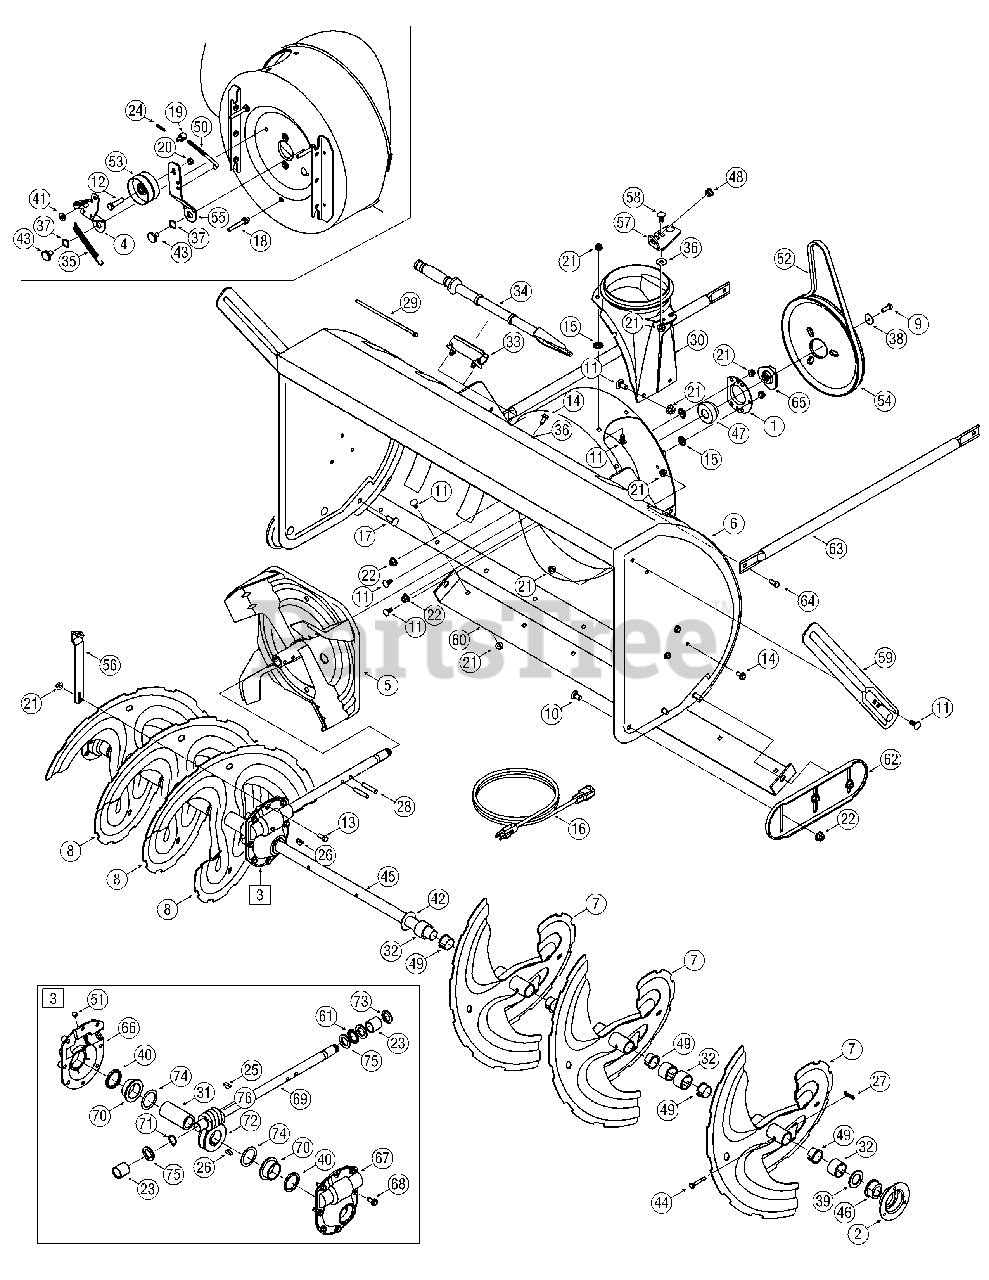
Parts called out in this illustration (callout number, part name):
1	Housing, Bearing
3	Gear Box Assembly, Auger
4	Bracket Assy, Auger Brake
9	Screw, 5/16-24 x .875
10	Bolt, Carriage, 3/8-16 x .750
11	Screw, Carriage, 5/16-18 x .75
12	Scr, Hex Cap, 3/8-24 x 1.5
13	Scr,Hex Cap, 5/16-18 x 1.00
14	Screw, 5/16-18 x .750
15	Nut, Push
16	Extension Cord, 110V
17	Bolt, Carriage, 3/8-16 x 1.0
18	Screw, 5/16-18 x .4300
19	Ferrule
20	Nut, Hex Lock, 3/8-24
21	Nut, Flnge Lk, 5/16-18
22	Nut, Flg Lk, 3/8-16
23	Sleeve
24	Pin, Internal Cotter
25	Key, Hi Pro, 3/16 x 3/4
26	Key, Woodruff,1/4 x 3/4
27	Pin, Bowtie Cotter
28	Pin, Spirol, 5/16 x 1.75
29	Tie, Cable
30	Adapter, Chute, 6"
31	Shf, Gear, Worm
32	Spacer, 1.0 x 1.5 x 1
33	Clip, Mounting
34	Tool, Cleanout
35	Spring, Extension
36	Washer, .349 x .879 x .063
37	Washer, .625 x .885 x .015
38	Washer, Flat, .34 x 1.50 x .150
39	Spacer, 1.004 x 1.375 x .25
40	Oil Seal
41	Washer, .344 x .75 x .12
42	Washer, 1.01 x 1.86 x .06
43	Screw, Shoulder, .625 x .17
44	Pin, Shear, .25 x 1.75
45	Axle, Spiral, 45"
46	Bearing, Flange w/Flats
47	Bearing, Self Aligning
48	Bushing, Nylon
49	Bushing, Flange, 1.051 x 1.16
50	Rod, Auger Idler
52	V Belt,1/2 x 44
53	Pulley, Flat Idler, 2.75 OD
54	Pulley, Auger Drive, 10.0
55	Bracket, Auger Idler
58	Screw, Carriage, 5/16-18 x 1.00
61	Brg, Thrust
65	Pulley, Adapter, .75 Dia.
66	Hsg Assy Auger RH (Inc. 40 & 70)
67	Hsg Assy Auger LH (Inc. 40 & 70)
68	Screw, LD, 5/16-18 x .750
69	Shf, Drive, Auger
70	Flange Bearing
71	Ext, Ret, Ring
72	Gear, Worm, LH
73	Seal, Oil
74	Washer, Flat, 1.52 ID x 2.0 OD
75	Washer, Flat, .88 ID x .38 OD
76	Gear, Worm, Dbl Thread
